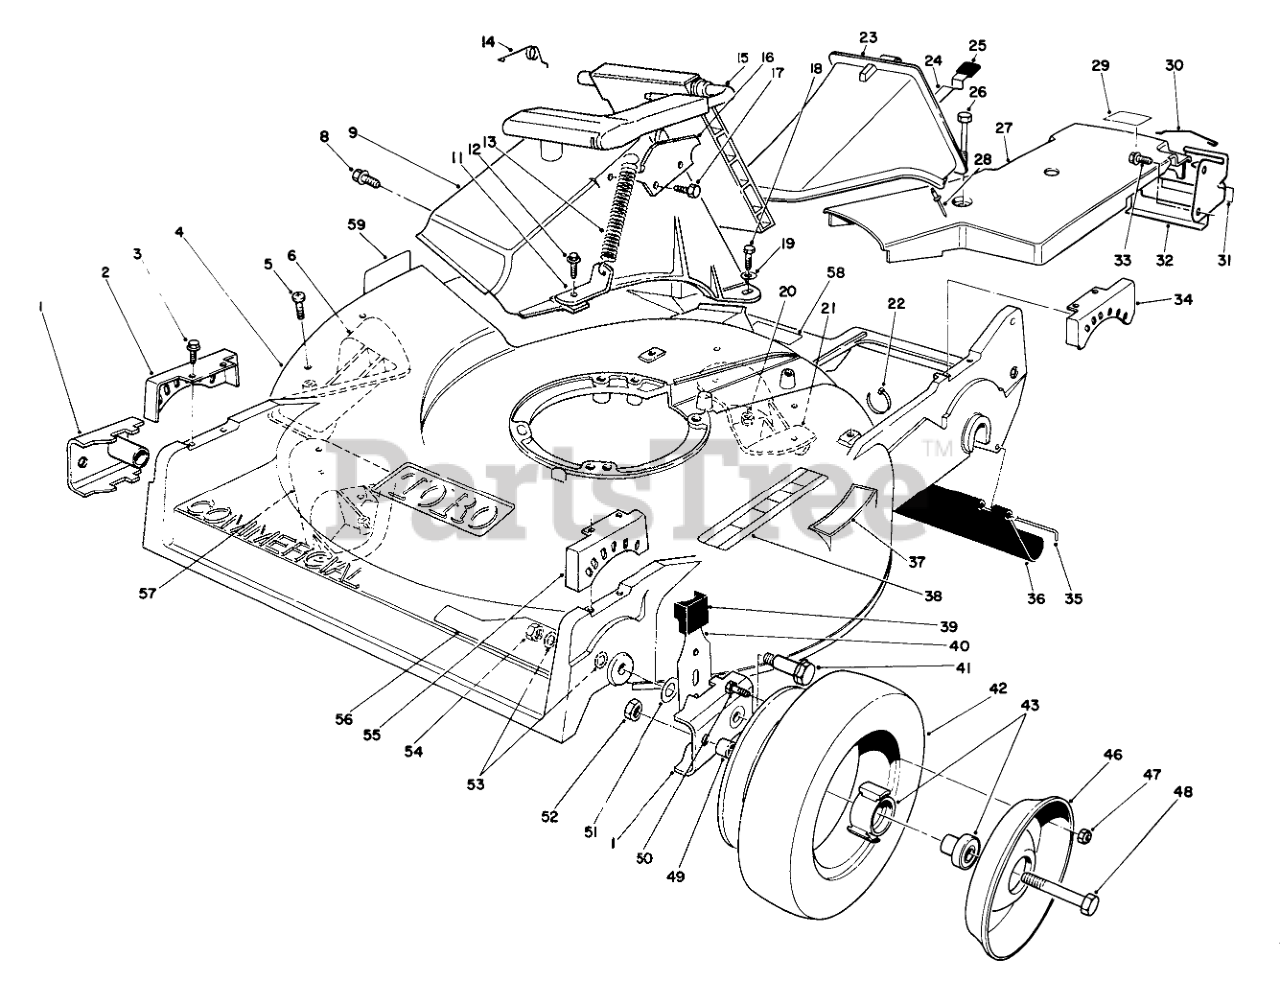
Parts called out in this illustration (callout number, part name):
1	ARM-PIVOT, FRONT
2	QUADRANT-FRONT, RH
3	SCREW-HWHTF
4	Housing-Commercial (Incl. Ref. #37, 38, & 59)
5	SCREW-PPH
6	KICKER-RH
8	SCREW AND WASHER ASM
9	TUNNEL-DISCHARGE
11	BRACKET-SPRING
12	SCREW-HWH
13	SPRING-DOOR
14	RETAINER-DOOR
15	DOOR ASSEMBLY
16	DOOR LATCH PLATE
17	SCREW-PLASTITE
18	SCREW-HH
19	WASHER-FLAT
20	NUT-LOCK, NI
21	KICKER-REAR
22	TIE-CABLE
23	Plug Assembly (Incl. Ref. #24, 25, & 28)
24	LATCH-PLUG, DISCHARGE
25	GRIP-LATCH
26	SCREW-HHFTF
27	COVER-BELT
28	RIVET-HEAD, FLAT
29	Label-Grease
30	RETAINER-CABLE
31	DECAL-POSITION, GEAR
32	BRACKET-ADJUSTMENT, TRACTION
33	SCREW-HWHTF
34	QUADRANT-REAR, LH
35	ROD-SHIELD
36	SHIELD-TRAILING
37	DECAL - STEP PAD INT'L
38	DECAL - DANGER
39	KNOB-ARM
40	FRONT SPRING ARM ASM
41	BOLT-WHEEL
43	Hub Ass-y
46	Wheel-Half
47	NUT-LOCK, NI
48	SCREW-HH
49	SPACER-WHEEL
50	SCREW-HH
51	WASHER-THRUST
52	NUT-LOCK, CONE
53	WASHER
54	NUT-LOCK
55	QUADRANT-FRONT, LH
56	DECAL - DECK
57	KICKER-FRONT
58	DECAL FRENCH REGUL.
59	DECAL - DIN/DANGER
